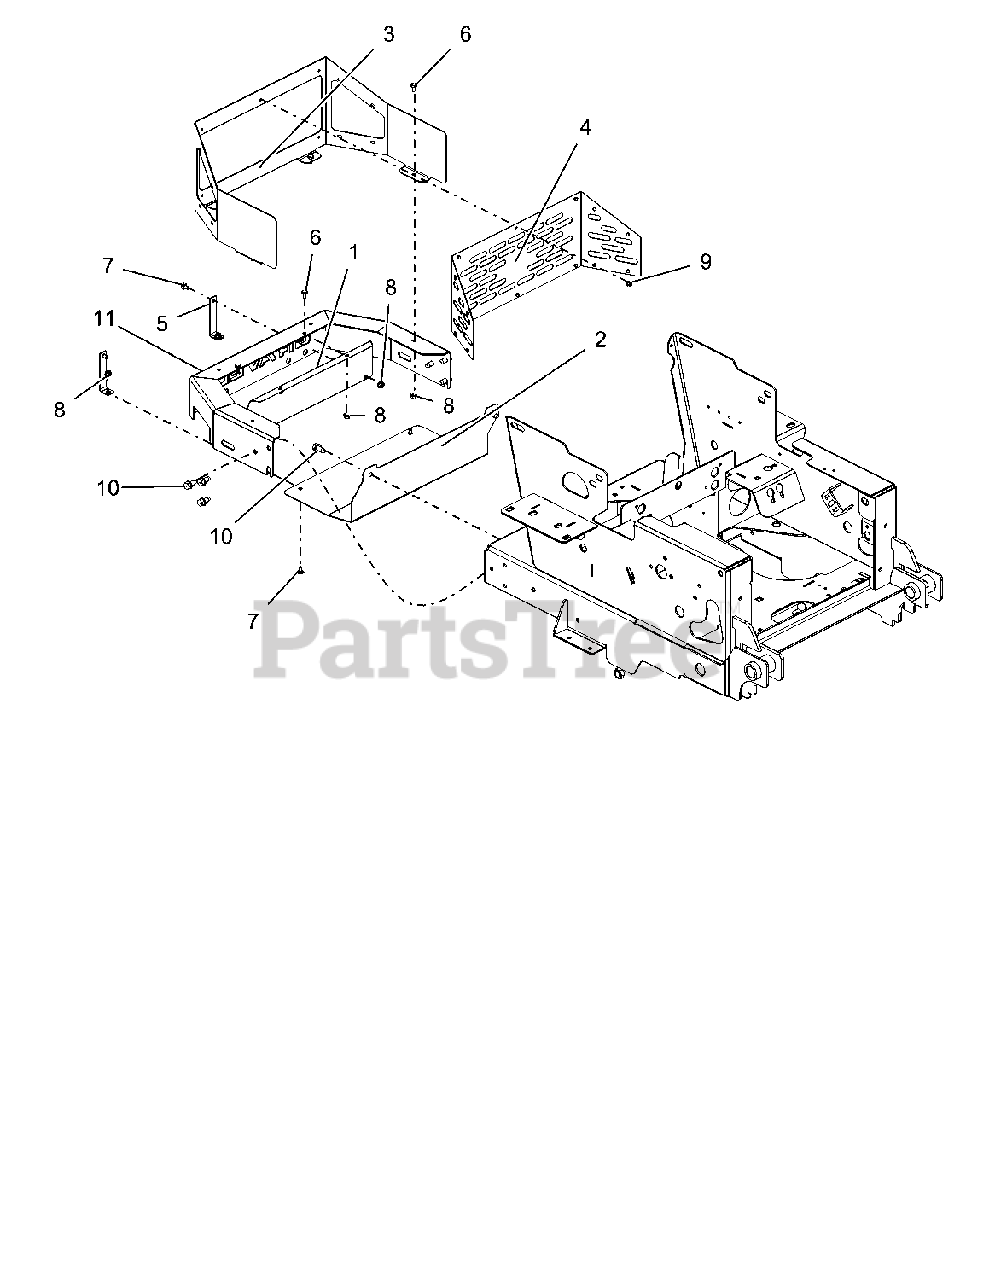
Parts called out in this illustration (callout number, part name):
1	BAFFLE, BUMPER INSERT
2	GUARD, EXHAUST HEAT
3	WRAP, OUTER ENGINE (RED)
4	WRAP, ENGINE INNER - GRAVELY
5	SUPPORT, HEAT SHIELD (BLACK)
6	BLT-HEX .25-20X.50 GR5 YWZC
7	BLT-RDHDSQNK .25-20X.50 G5 Y
8	NUT, LK-TOP-FLG .25-20 YWZC
9	RVT, POP .187x.250 AL/AL
10	SCR-TAP .38-16X.75 HWH TR YWZ
11	KIT, GRAVELY BUMPER W/SAFETY DECALS (INCLUDES 04822953)
